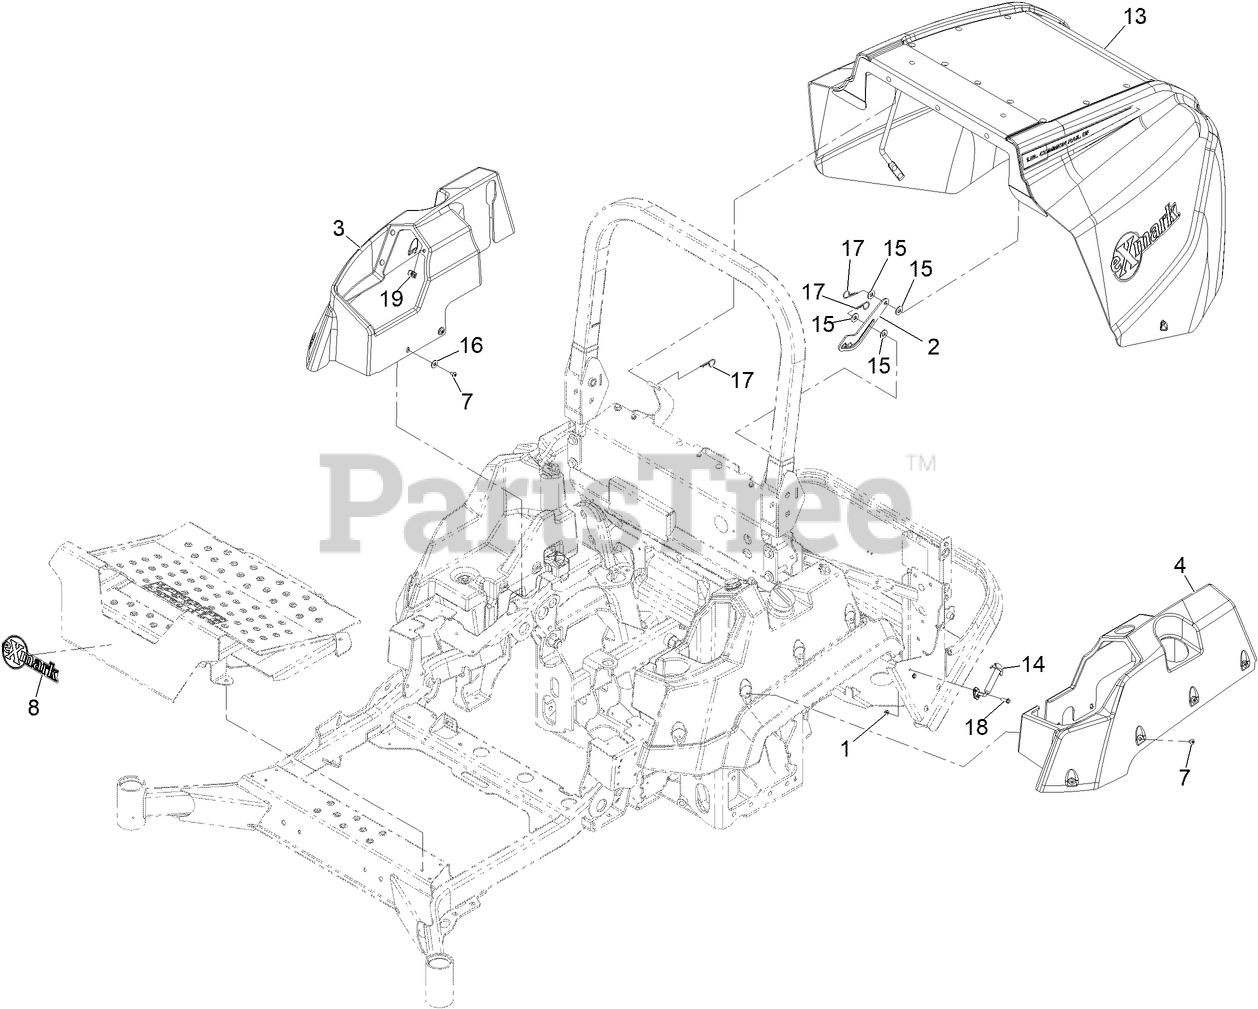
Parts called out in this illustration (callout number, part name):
2	PROP-HOOD
3	COVER-TANK, RH
4	COVER-TANK, LH
7	SCREW-TORX
8	DECAL-EXMARK
13	ASM, HOOD LZSD
14	LATCH-HOOK
15	WASHER-FLAT
16	WASHER-FLAT
17	PIN-COTTER, HAIR
18	SCREW-HWH
